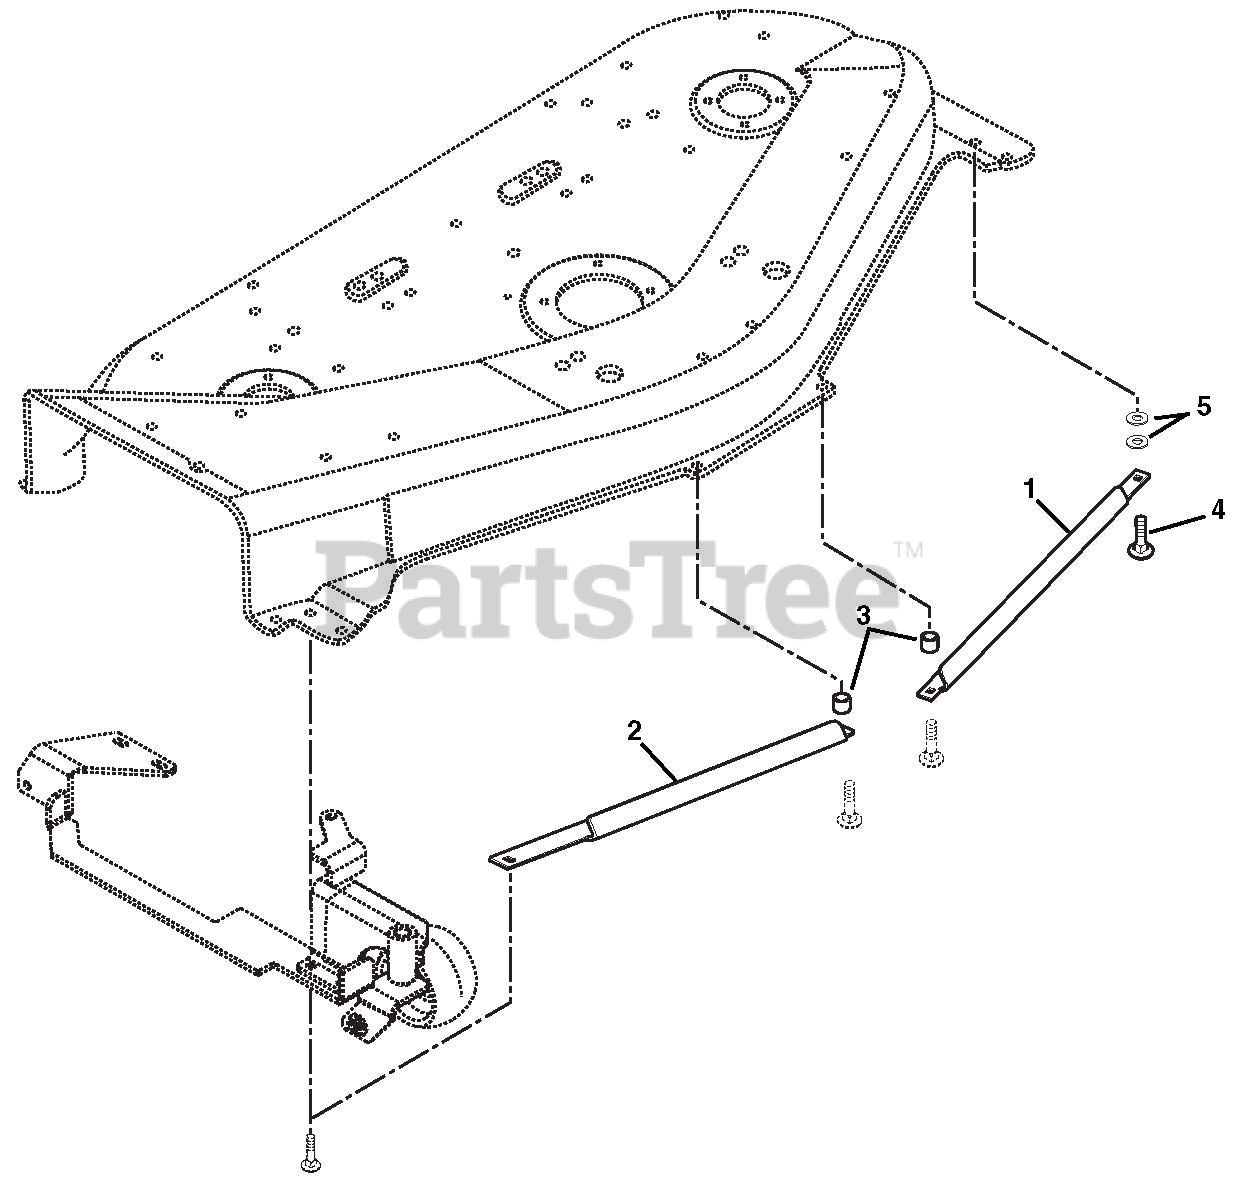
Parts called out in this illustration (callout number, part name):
1	GUARD - FOOT - LEFT - ORANGE
2	GUARD - FOOR - RIGHT - ORANGE
3	SPACER .375 X .625 X .500
4	@BLT-RDHDSQNK .31-18X1.25 G5YZ
5	WSHR-FL-STL .390X.75X.125 YWZC
